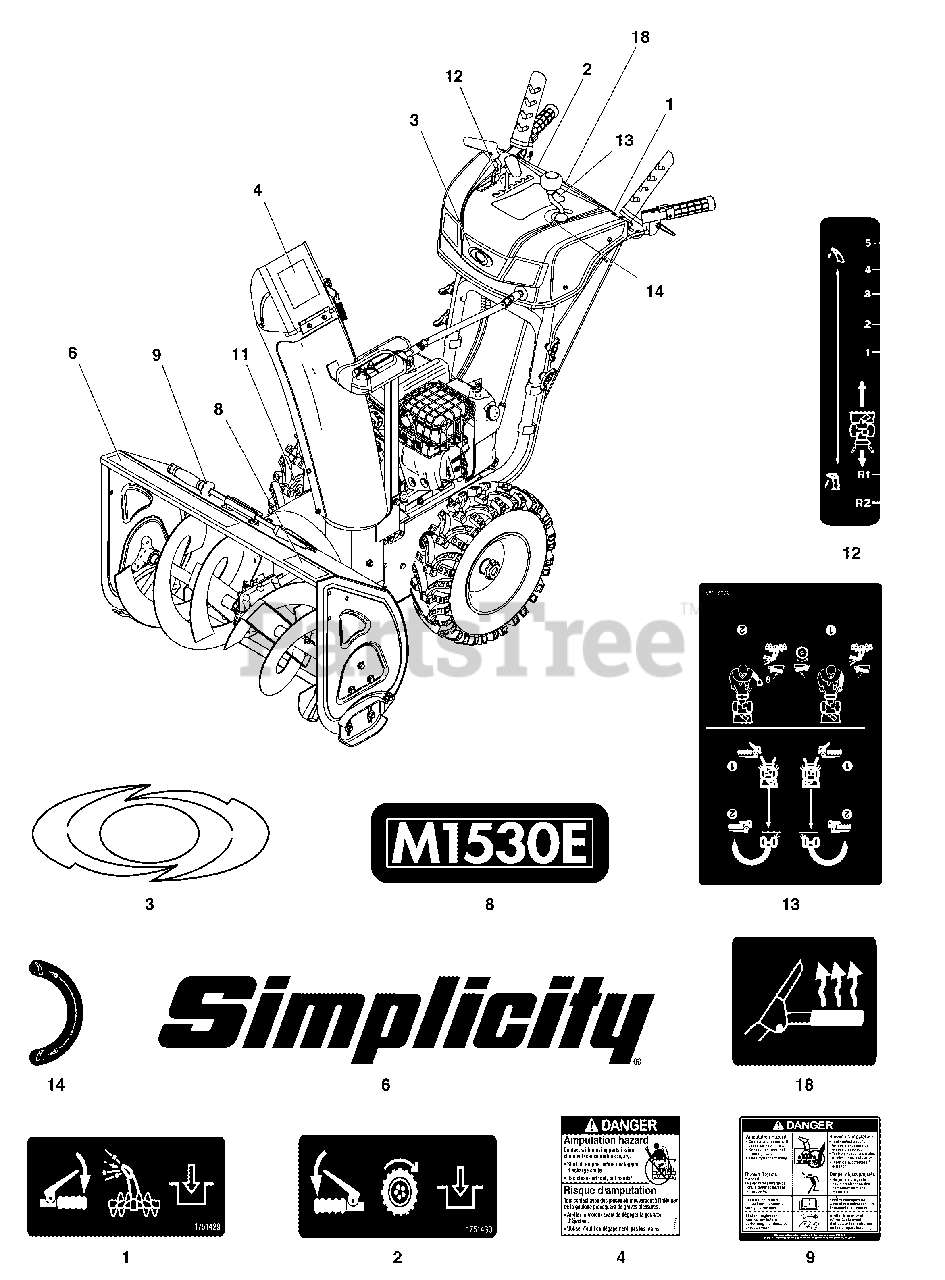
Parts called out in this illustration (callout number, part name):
1	DECAL, Auger Control
2	DECAL, Traction Control
3	DECAL, 3D, Logo, Simplicity
4	DECAL, Danger Chute Warning, FR/ENG
6	DECAL, Model, SMI Logo 10.47" Long
8	DECAL, Model M1530E
9	DECAL, Danger Foot, FR/ENG
11	DECAL, I.D. Plate
12	DECAL, 1-6 Transmission Speed Control
13	DECAL, Free Hand Operation
14	DECAL, Chute Rotation
18	DECAL, Heated Hand Grip Switch
